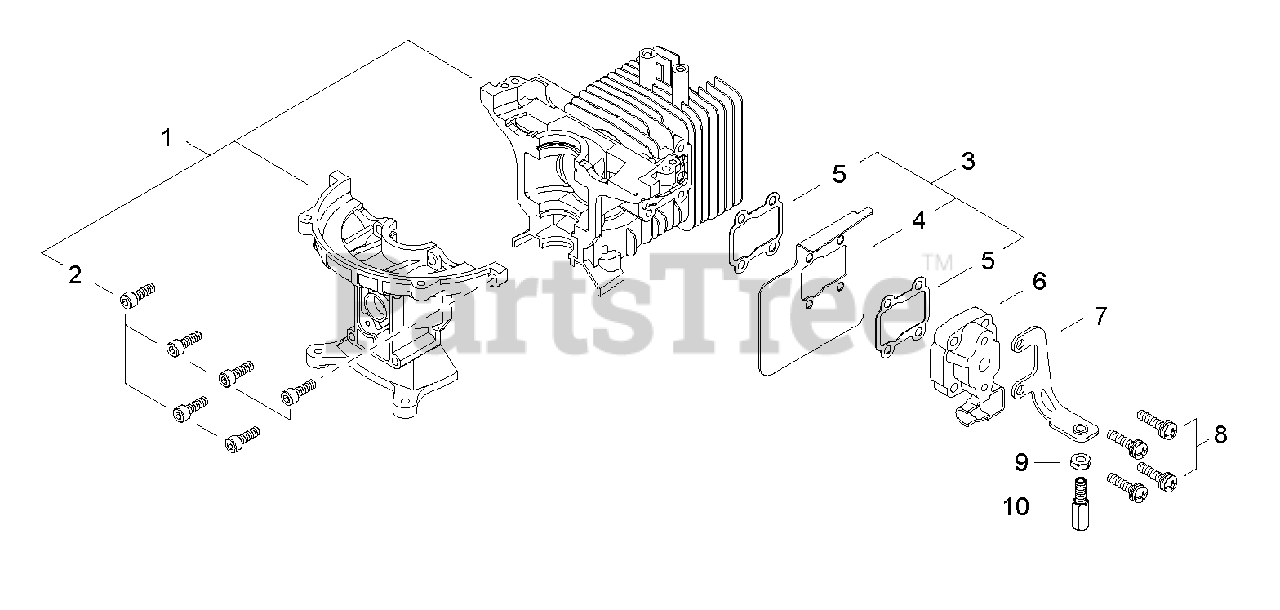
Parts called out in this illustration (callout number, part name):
1	CRANKCASE ASSY
2	SCREW - 5X16
3	INTAKE SHIELD ASSY
4	DEFLECTOR, HEAT
5	SHIELD, INTAKE
6	INSULATOR
7	BRACKET, THROTTLE CABLE
8	SCREW - 5X22
9	LOCKNUT - 6
10	NUT, CABLE ADJUST
